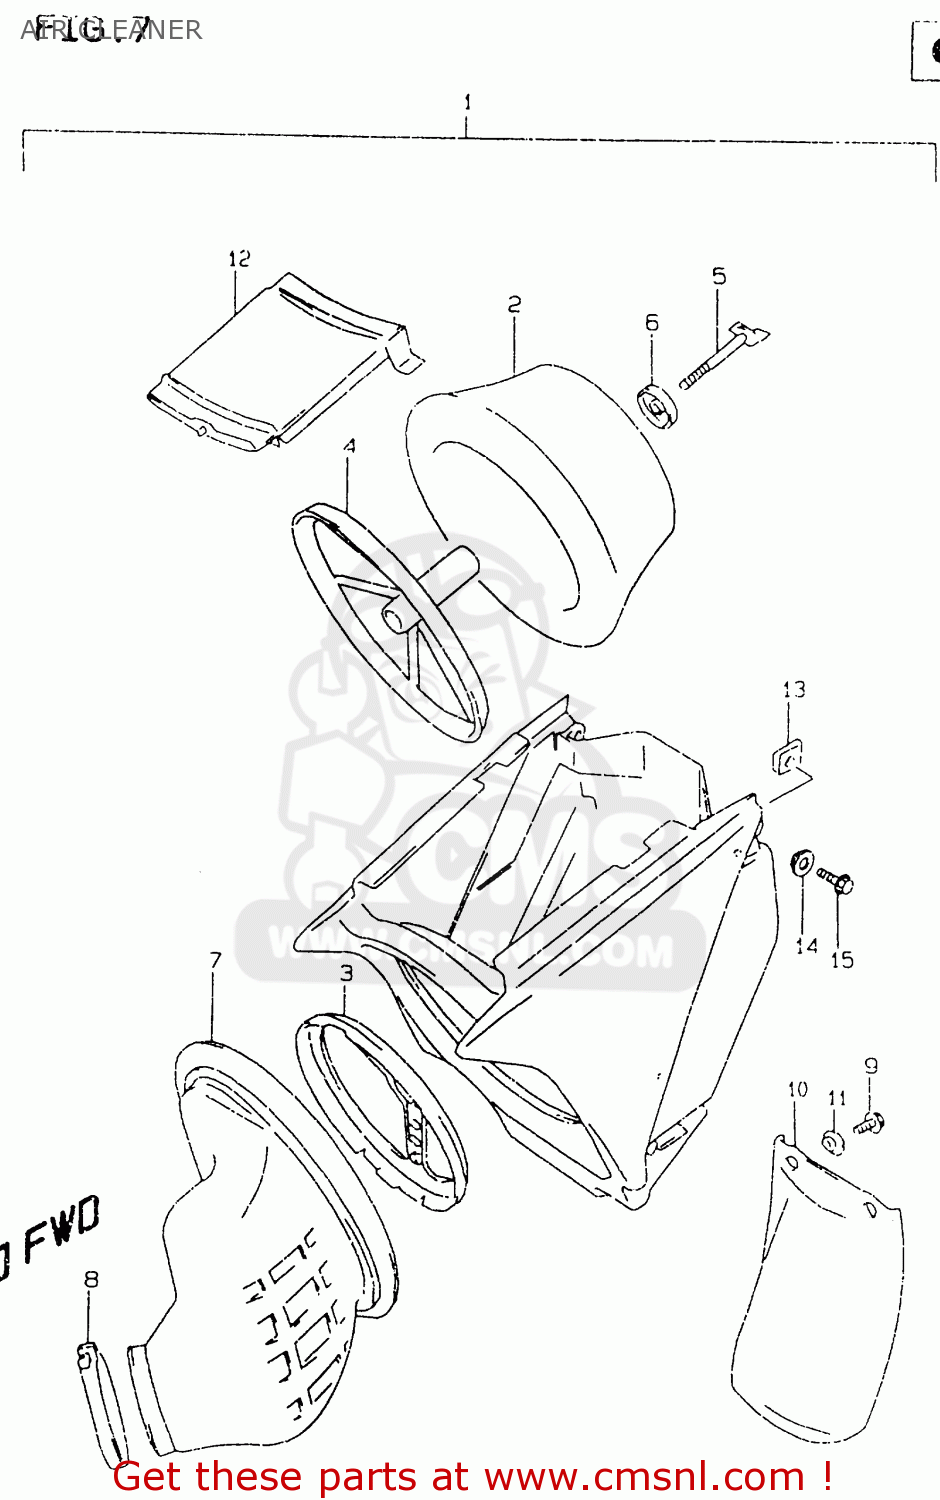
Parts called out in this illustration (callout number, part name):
1	CLEANER ASSEMBLY,AIR
2	FILTER ASSY
3	BASE,FILTER
4	HOLDER,FILTER
5	BOLT,WING
6	WASHER,AIR CLEANER
7	TUBE,OUTLET
8	CLAMP
9	BOLT
10	MUDGUARD
11	COLLAR
12	CAP,AIR CLEANER
13	HOLDER,REAR BU
14	WASHER
15	SCREW
